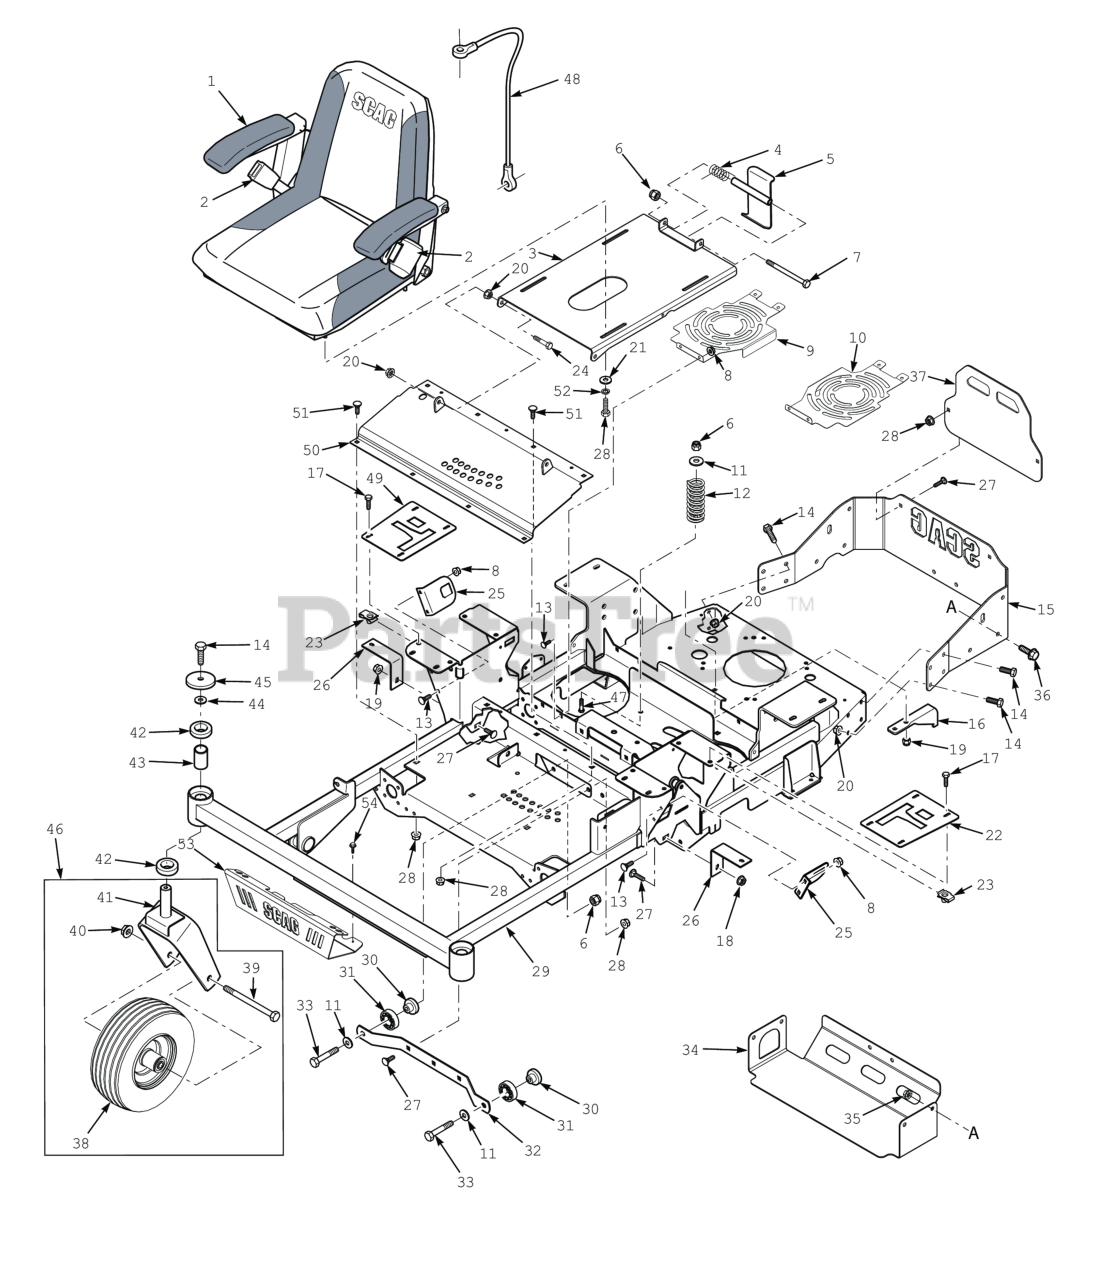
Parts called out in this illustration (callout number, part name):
1	Seat Assembly
2	Seat Belt Assembly, Retractable
3	Seat Base w/Decal
4	Spring, Seat Latch
5	Weldment, Seat Latch
6	HEX NUT, ELASTIC STOP LOCK, 3/8-16
7	Bolt, 3/8-16 x 6.00" Hex Head
8	NUT, 1/4-20 SERRATED FLANGE HEX HEAD
9	Fan Cover, RH
10	Fan Cover, LH
11	Flatwasher, 3/8" Special (.391 x .938 x .105)
12	Spring, Seat
13	Bolt, Carriage 1/4-20 x 1/2"
14	Capscrew, 3/8-16 x 1.0" Serrated Flange Hex Hd
15	Rear Bumper
16	Bracket, Anti-Rotation
17	CAP SCREW, 1/4-20 X 1" SERRATED FLANGE HEX
18	Nut, Flange Head Elastic Stop 5/16-18
19	HEX NUT, ELASTIC STOP LOCK, 5/16-18
20	NUT, 3/8-16 SERRATED FLANGE HEX HEAD
21	Flatwasher, 5/16-.375 x .875 x .083 (35BV & 37BV-EFI)
22	Control Plate LH (Black)
23	Bolt, Hex Head 3/8-16 x 1"
24	Bolt, Hex Head 3/8-16 x 1-1/2" B&S 32BV
25	Bracket, Switch Mount
26	Bracket, Tank Mount
27	Bolt, 5/16-18 x .75 RHSN Carriage
28	BOLT, SERRATED FLANGE HEX HEAD 5/16-18 X 3/4"
29	Main Frame w/Decals
30	Spacer, Bearing
31	Bearing
32	Support, Deck Guide
33	Bolt, Hex Head 3/8-16 x 1-3/4" (Kohler EFI)
34	Heatshield
35	NUT, 3/8-16 SERRATED FLANGE HEX HEAD
36	Capscrew, 3/8-16 x 1.0" Serrated Flange Hex Hd
37	Guard, Engine, (Scag Gold)
38	Caster Wheel Assembly (INCL. Rim - 486311)
39	Bolt, Hex Head 1/2-13 x 7-1/2" (48"/52")
40	HEX LOCKNUT, ELASTIC STOP, 1/2-13
41	Yoke, Caster Wheel
42	Bearing
43	Spacer, Caster Bearing
44	Flatwasher, 7/16" (.500 x 1.25 x .083")
45	Flatwasher, 3/8-.406 x 2.25" x .1875
46	Caster Wheel Assembly w/Yoke
47	SHORT SQ. NECK CARRIAGE BOLT, 3/8-16 X 1-1/4"
48	Cable, Seat Stop
49	Control Plate RH (Black)
50	Weldment, Deck Lift Cover w/Decal
51	Carriage Bolt, 5/16-18 x 1/2"
52	Lockwasher, 5/16 (.317 x .586 x .078) Helical Spring
53	Bumper. Front
54	Screw, 1/4-20 x .375"
